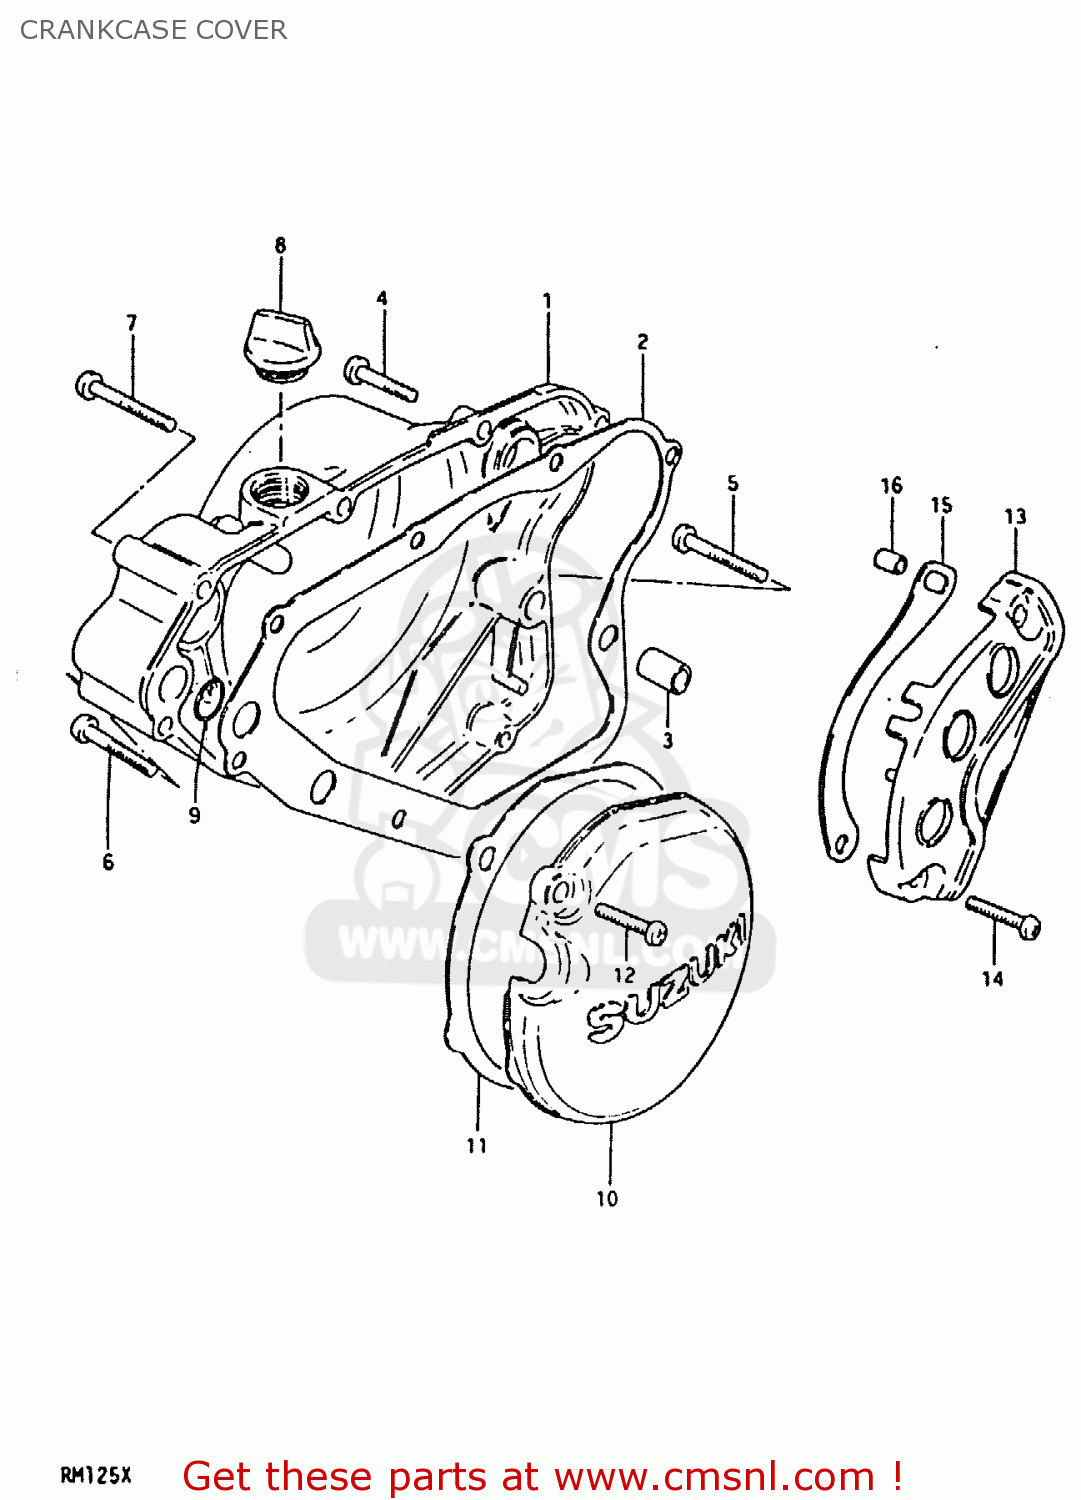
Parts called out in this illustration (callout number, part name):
1	COVER,CLUTCH
2	GASKET,CLUTCH COVER (MCA)
3	PIN
4	SCREW
5	SCREW (6X45)
6	CROSS SCREW (6 X 75)
7	SCREW 6X85
8	PLUG,OIL FILTER
9	O RING(D:1.9,ID:14.5)
10	COVER,MAGNETO
11	GASKET,MAGNETO COVER (MCA)
12	SCREW
13	COVER,ENGINE SPROCKET
14	BOLT
15	PLATE,CHAIN FRONT GUIDE
16	SPACER(6.5X10.5X12)
